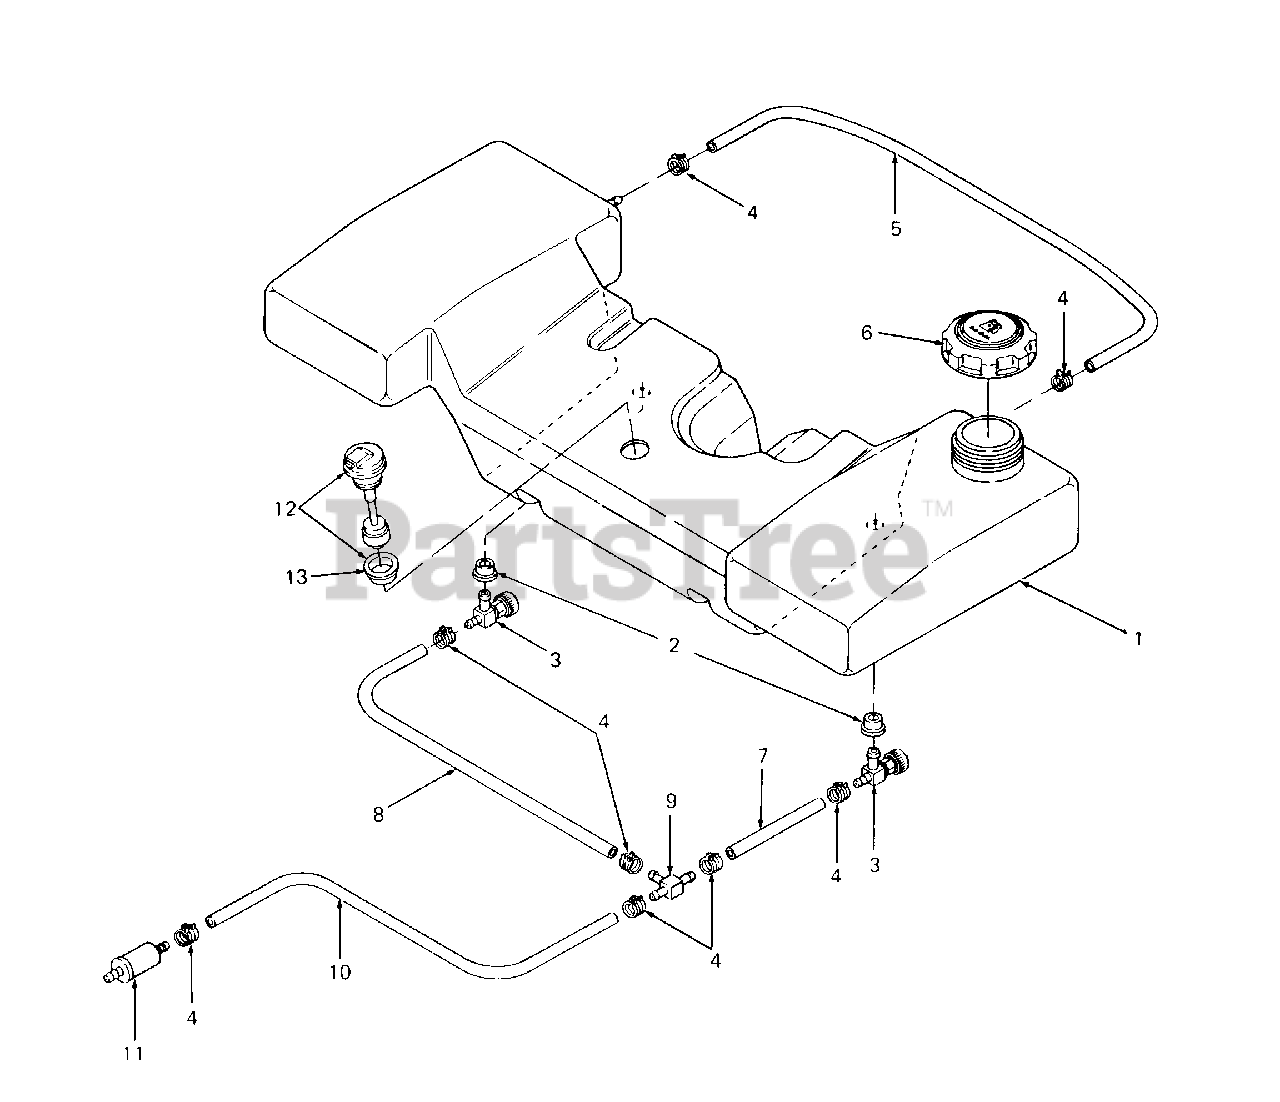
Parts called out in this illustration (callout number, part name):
1	Tank,Fuel
2	Bushing
3	Valve, Fuel Shutoff
4	Clamp, Hose
5	Line, Fuel -24" Lg
6	Cap, Fuel
7	Line, Fuel -5" Lg
8	Line, Fuel -19" Lg
9	T-Fitting
10	Line, Fuel -41" Lg
11	Filter, Fuel
12	Sensor, Low Fuel
13	Bushing, Rubber
